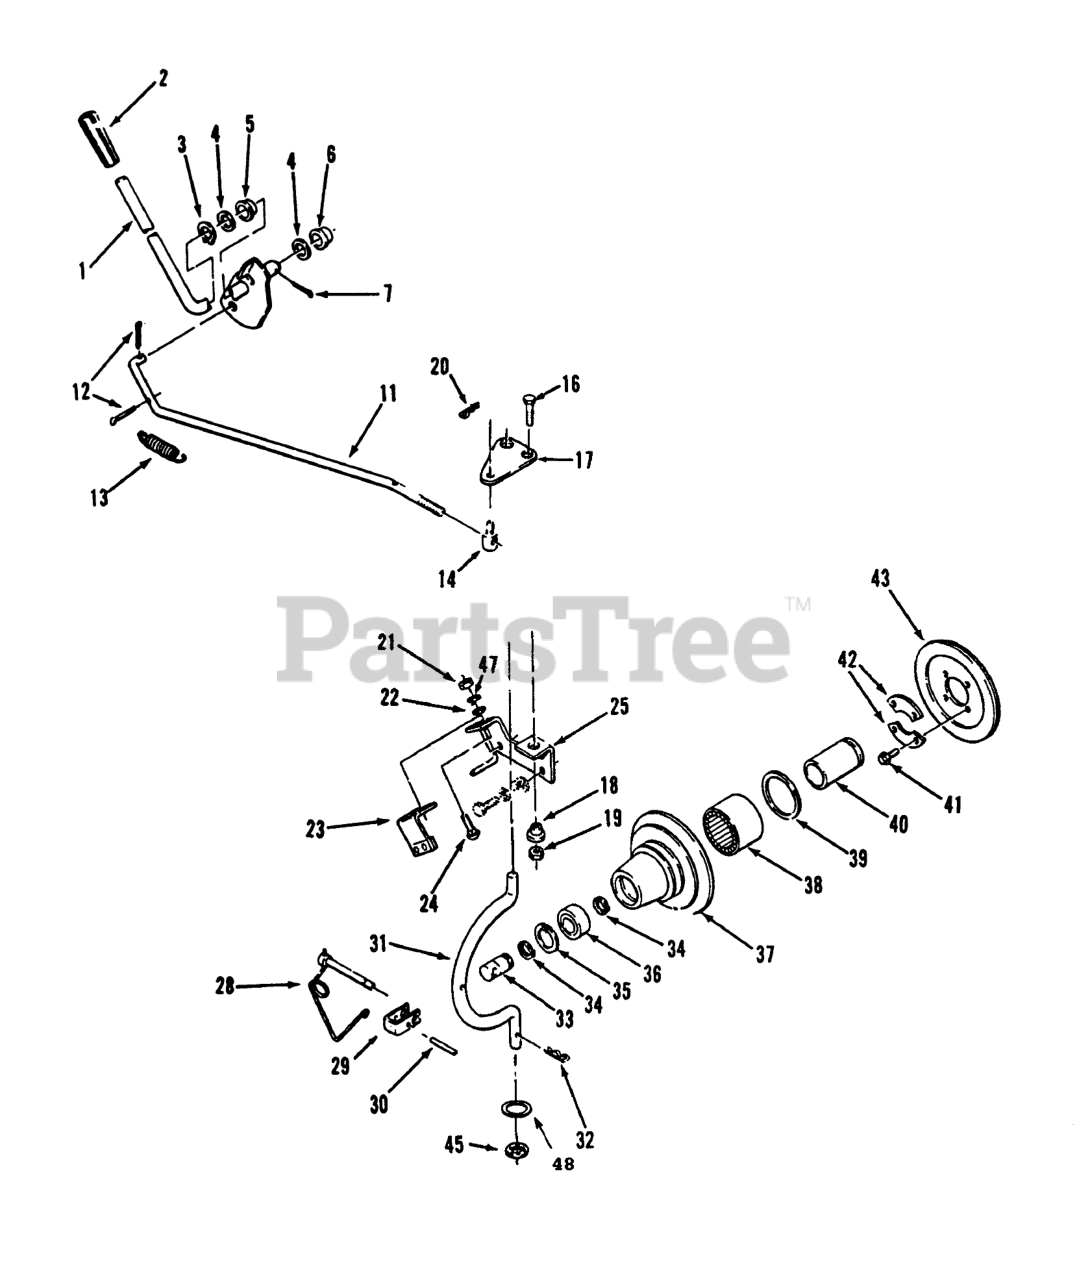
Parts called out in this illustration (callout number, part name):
1	ASSY PTO CLUTCH LEVE
2	GRIP
3	Grip Ring
4	SHIM-WASHER
5	BUSHING-NYLINER
6	NYLINER BUSHING
7	PIN-COTTER
11	ROD-PTO CLUTCH
12	PIN-COTTER
13	SPRING
14	TRUNNION
16	SCREW-HH
17	PLATE
18	SPACER-LIFT LINK
19	NUT-LOCK, NI
20	Hairpin Cotter
21	NUT-JAM
22	WASHER-FLAT
23	ASM-Bracket
24	SCREW-CARR
25	BRACKET WA ENG. B
28	LOCKING PIN ASM
29	CLEVIS
31	ROD-HOUSING
32	Hairpin
33	SHAFT-PTO
34	Ring-Snap
35	Ring-Snap
36	BEARING-BALL
37	Housing-Clutch
38	BRG-NEEDLE OPEN END
39	Seal
40	RACE-BEARING
41	SCREW-HH
42	RETAINER
43	Facing-Clutch
45	RING-REINFORCED CIRC
47	WASHER-LOCK
48	Washer-Flat
